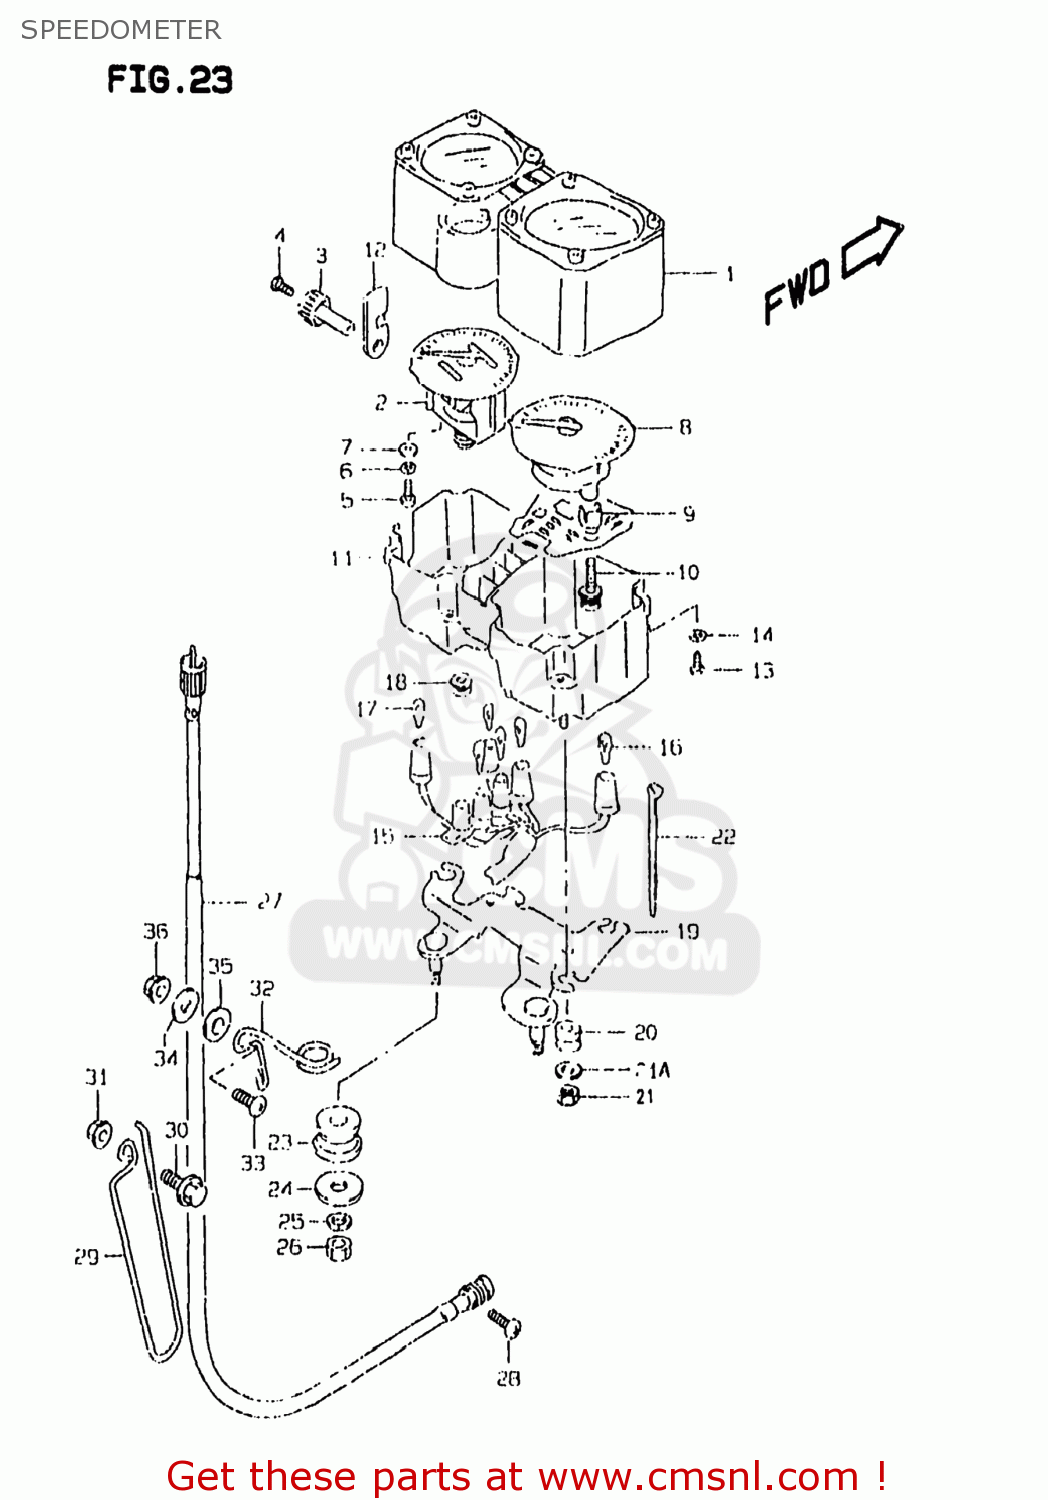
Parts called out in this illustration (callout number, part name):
1	HOOD,METER
2	SPEEDOMETER
3	KNOB,TRIP
4	SCREW,TRIP KNOB
5	SCREW
6	WASHER,LOCK
7	WASHER
8	TACHOMETER
9	SPACER
10	SCREW
11	CASE,METER
12	CUSHION,METER
13	SCREW
14	WASHER,LOCK
15	SOCKET,METER
16	BULB(12V3W,WB371,T7)
17	BULB(12V1.7W,WB372,T7)
18	CAP
19	BRACKET
20	CUSHION,METER
21	NUT
21A	WASHER(5.5X16X1.2)
22	CLAMP(L:97)
23	CUSHION,METER BRACKET
24	WASHER(8.5X28X1.6)
25	WASHER,LOCK
26	NUT
27	CABLE ASSEMBLY,SPEEDOMETER
28	SCREW
29	GUIDE,METER CABLE NO.2
30	BOLT(6X20)
31	NUT
32	GUIDE,SPEEDOMETER CABLE
33	SCREW
34	WASHER(6.5X18X1.6)
35	WASHER
36	NUT 6MM
